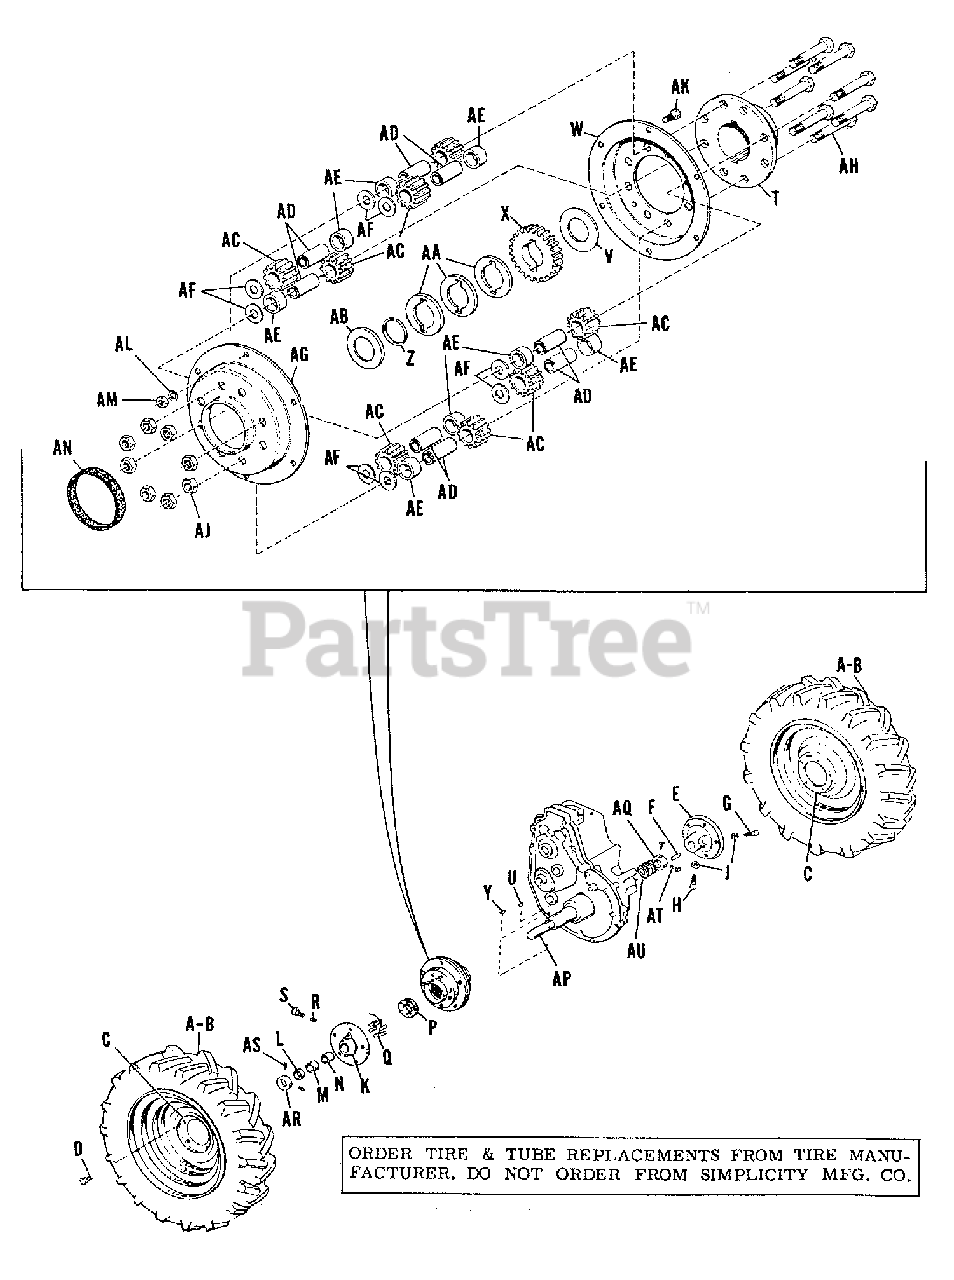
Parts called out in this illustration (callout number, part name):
E	HUB, Wheel, L.H.
G	SCREW, Set, Square Head, Cone, 3/8"-16 NC x 1-1/2" LG
H	SCREW, Set, Square Head, Cup, 3/8"-16 nc X 1" LG
J	NUT, Hex, Jam, 3/8"-16 NC
K	HUB ASSEMBLY, (Complete w/Brgs, Nylon, Plugs, Gear, Etc.)
M	BEARING, Nylon
P	GEAR, Differential
Q	PIN, Roll
T	CARRIER, Differential
V	WASHER, Axle
W	COVER, Differential
X	GEAR, Differential
Y	KEY, Hi-Pro
Z	RING, Retaining
AA	WASHER, Axle
AB	WASHER, Axle
AC	PINION, Differential
AD	SPINDLE, Pinion Differential
AE	SPACER, Differential
AF	WASHER, Plain
AG	COVER, Differential
AH	SCREW, Cap, Hex, 3/8"-16 NC x 2-1/4" LG
AJ	NUT, Lock, Full Hex, 3/8"-16 NC
AK	SCREW, Cap, Hex, 1/4"-20 NC x 1/2" LG
AL	WASHER, Lock, 1/4"
AM	NUT, Full, Hex, 1/4"-20 NC
AN	SEAL, Differential Cover
AP	AXLE, Rear
AQ	COLLAR, Axle
AR	COLLAR, Axle
AS	SCREW, Set, Cup Point, Hollow Head, 5/16"-18 NC x 5/16" LG
AT	SCREW, Set, Cup Point, Square Head, 5/16"-18 NC x 1/2" LG
